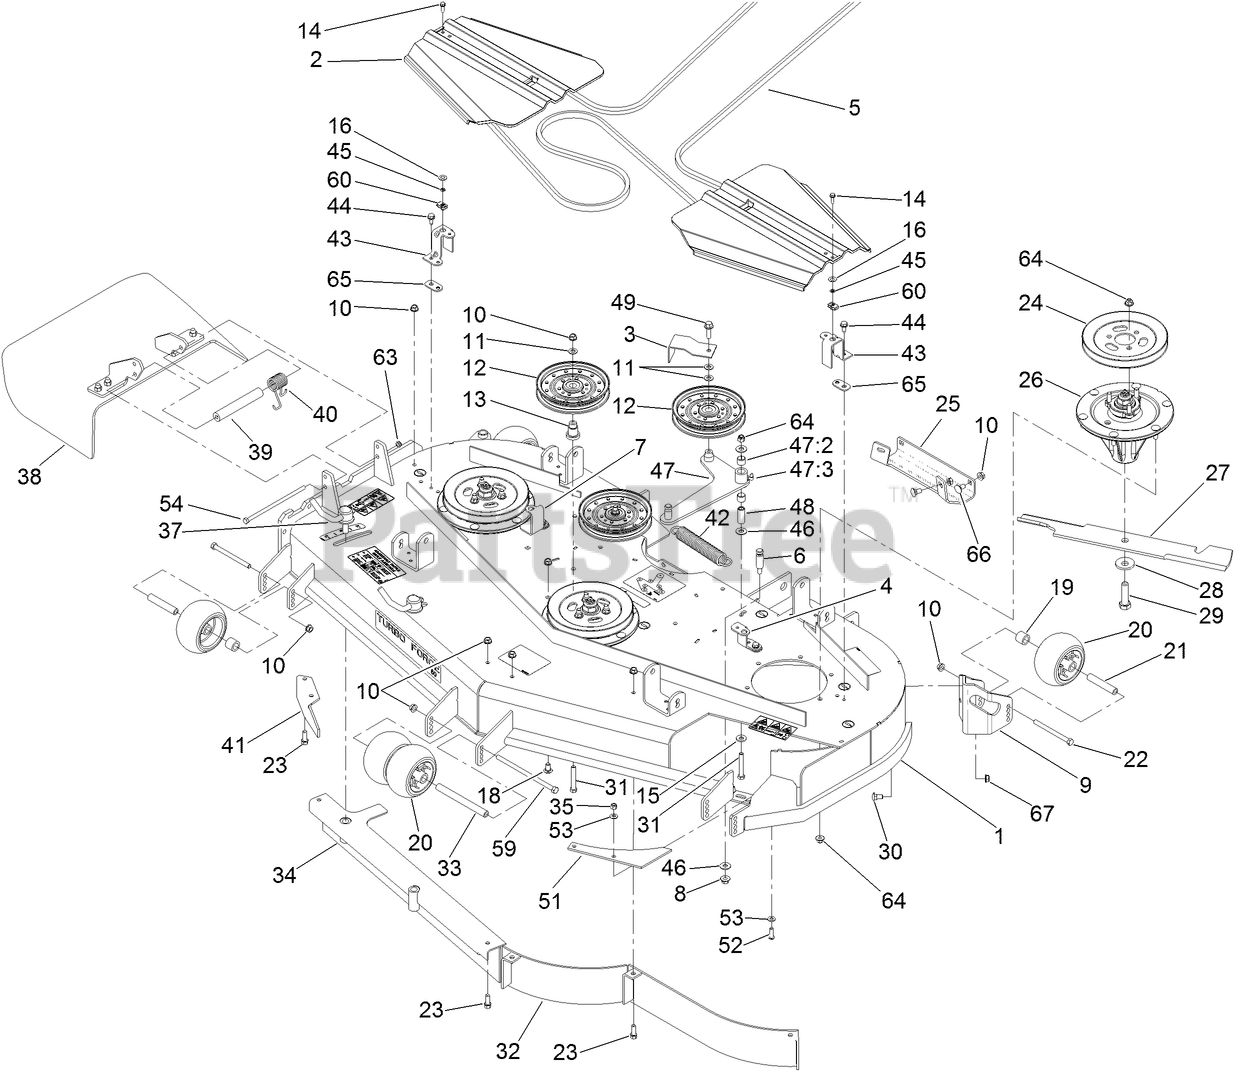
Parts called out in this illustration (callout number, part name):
1	DECK DECAL ASM
2	COVER-BELT
3	GUIDE-BELT
4	BRACKET-COVER, TALL
5	BELT-V
6	PIN-THREADED, SPRING ANCHOR
7	BRACKET-COVER
8	NUT-HF
9	MOUNT-WHEEL, LH
10	NUT-HHF, WHIZ
11	WASHER-FLAT
12	Idler-Flat
13	MOUNT-PULLEY
14	SCREW-HWH
15	WASHER-BELLEVILLE
16	WASHER-THRUST
18	SCREW-CARR
19	TUBE-SPACER
20	ROLLER-SCALP, ANTI
21	TUBE-SPANNER
22	SCREW-HH
23	SCREW-HWH
24	PULLEY
25	Plate-Skid
26	SPINDLE ASM
27	BLADE-HI FLOW
28	Washer-Blade Bolt, Heavy
29	SCREW-BLADE
30	SCREW-CARR
31	SCREW-HH
33	SPACER-WHEEL
35	NUT-LOCK, NI
37	LEVER ASM
38	RUBBER DEFLECTOR ASM
39	SPACER
40	SPRING-TORSION
41	BAFFLE-DISCHARGE
42	SPRING-EXTENSION
43	BRACKET-COVER
44	SCREW-HWHTF
45	NUT-RETAINER
46	WASHER-FLAT
47	DECK IDLER ARM ASM
47:2	SLEEVE-BEARING
47:3	FITTING-GREASE, 90 DEG
48	BUSHING
49	SCREW-HHF
51	PLATE-TURBO
52	SCREW-HSBH
53	WASHER-SPRING
54	SCREW-HH
59	SCREW-HH
63	NUT-LOCK, NI
64	NUT-HF, NI
65	SPACER-BELT COVER
66	SCREW-CARR
67	NUT-LOCK, NI
